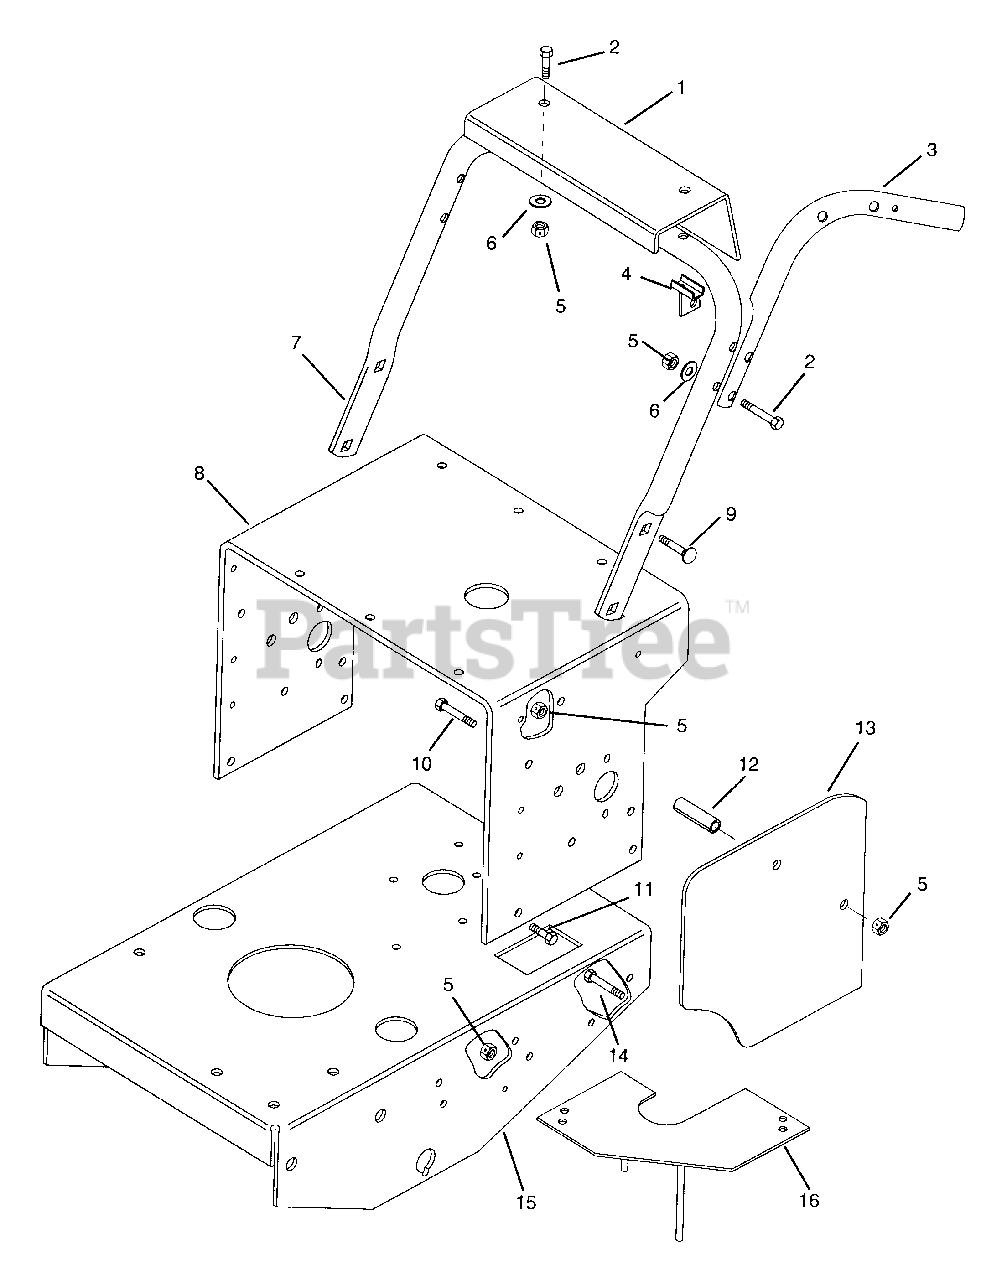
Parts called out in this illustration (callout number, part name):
1	PNL,INSTRUMENT
2	@BLT-HEX .38-16X2.00 GR5 YWZC
3	HANDLEBAR L.H.
4	PTO LEVER MTG BKT
5	@NUT-LK-CTR .38-16 YWZC
6	@WSHR-FL-STL.406X.812X.065 YWZ
7	LOWER HANDLEBAR, PRO 150
8	FRAME, TOP - PRO 150
9	@BLT-RDHDSQNK .38-16X1.00 G2YZ
10	@BLT-HEX .38-16X4.00 GR5 YWZC
11	@BLT-HEX .38-16X1.00 GR5 YWZC
12	BSHG, SPACER, 3.25X3/8IDX5/8OD
13	GUARD, DRIVE.PRO-150 SIDE CVR
14	@BLT-HEX .38-16X1.50 GR5 YWZC
15	FRAME, MAIN - PRO 150
16	WLDT, BELT FINGER, PRO-150
